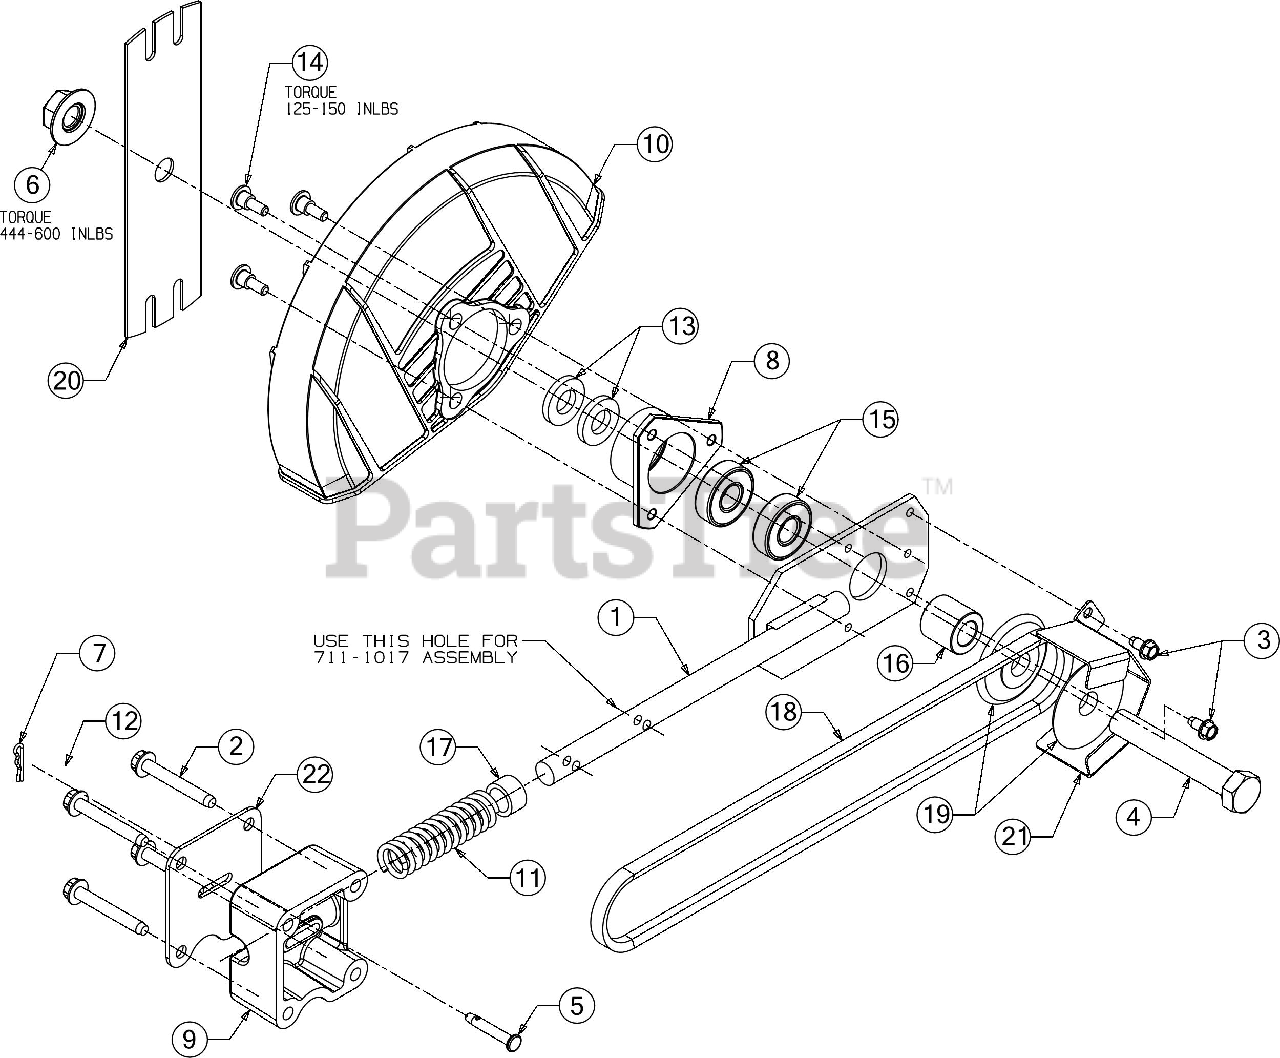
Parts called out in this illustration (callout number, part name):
1	BLADE PLATE ASSEMBLY
3	SCREW 1/4-20 X.500
4	SCREW 5/8-18 X 4 GR5
5	CLEVIS PIN
6	HEX NUT
7	COTTER PIN .072 DIA
8	BEARING CUP
9	BEARING BLOCK
10	BLADE GUARD
11	COMPRESSION SPRING
12	FLAT WASHER .283 ID X .749 X .030
13	FLAT WASHER .635 X 1.24 X .181
14	SHOULDER SCREW .375X.280:1/4-14
15	BALL BEARING
16	SPACER
17	SPACER
18	BELT 3L X 35.8
19	SHEAVE
20	EDGER BLADE
21	BELT GUARD-
22	COVER PLATE
